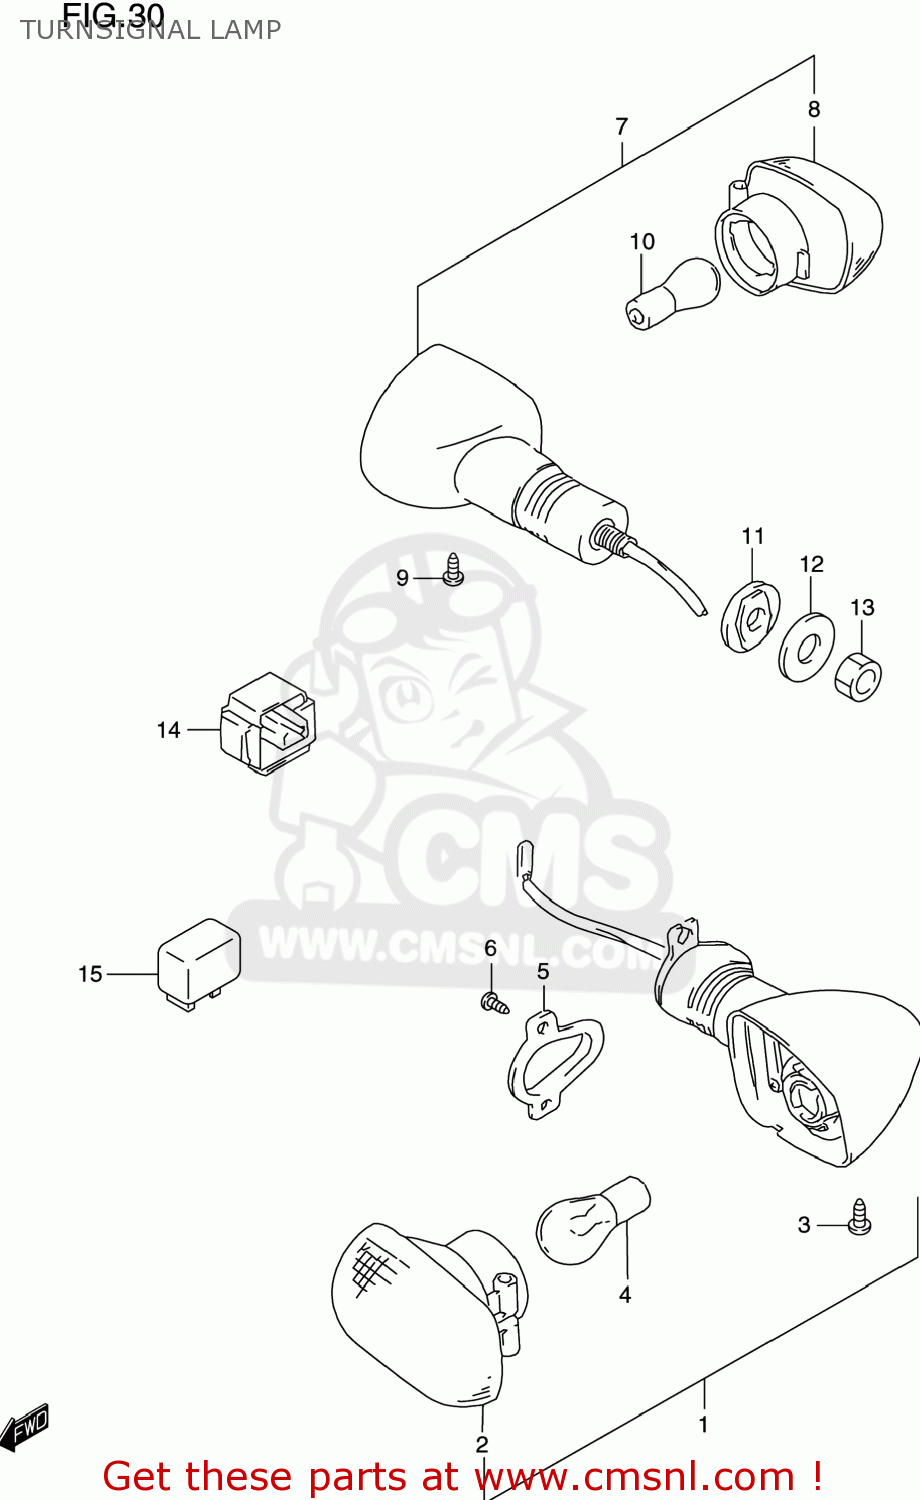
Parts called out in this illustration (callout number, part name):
1	LAMP ASSEMBLY,FRONT TURN SIGNAL
2	LAMP UNIT
3	SCREW
4	BULB(12V21W)
5	PLATE,FR TURNSIGNAL LAMP
6	SCREW
7	LAMP ASSY,RR TURNSIGNAL,R
8	LAMP UNIT
9	SCREW
10	BULB(12V21W)
11	SPACER,RR TURNSIGNAL
12	WASHER(10.5X30X2.3)
13	NUT
14	RELAY ASSY
15	RELAY ASSY,TURNSIGNAL LAMP
